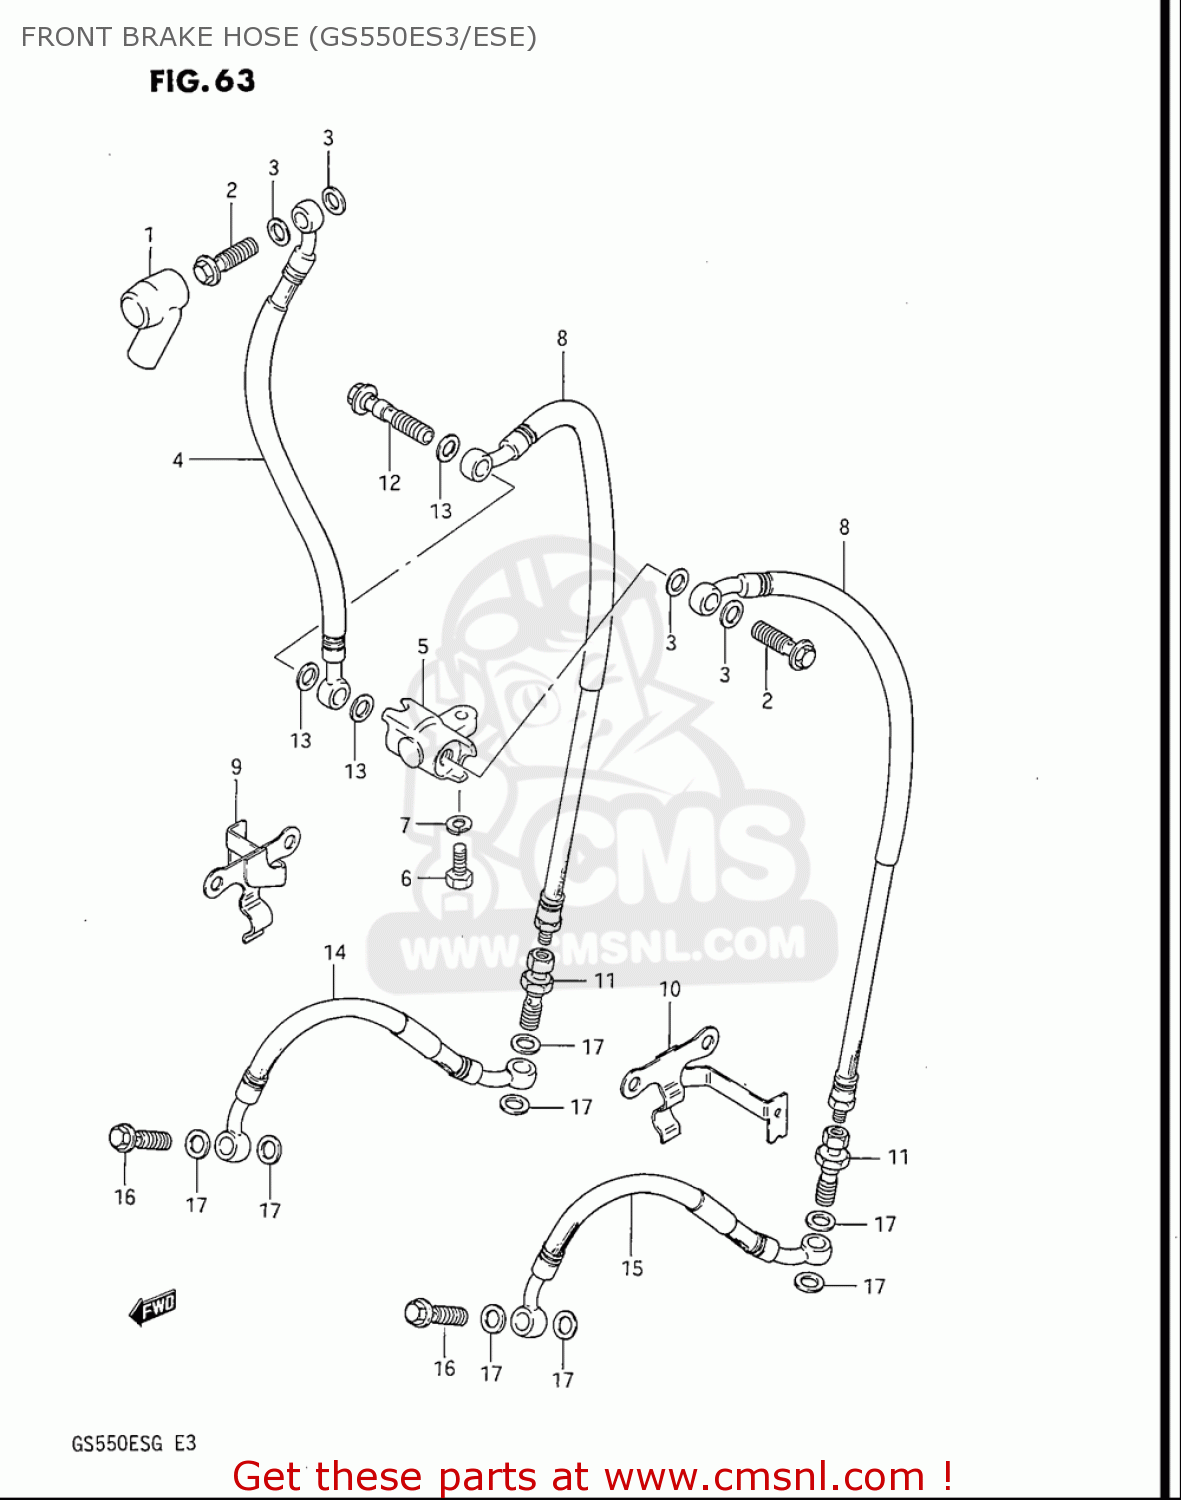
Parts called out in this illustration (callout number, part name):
1	BOOT,MASTER CYLINDER
2	BOLT UNION
3	WASHER(10X15X1.5)
4	HOSE,FRONT BRAKE NO.1
5	JOINT,BRAKE HOSE
6	BOLT
7	WASHER,LOCK
11	ADAPTER,BRAKE HOSE
12	BOLT UNION
13	WASHER(10X15X1.5)
16	BOLT UNION
17	WASHER(10X15X1.5)
